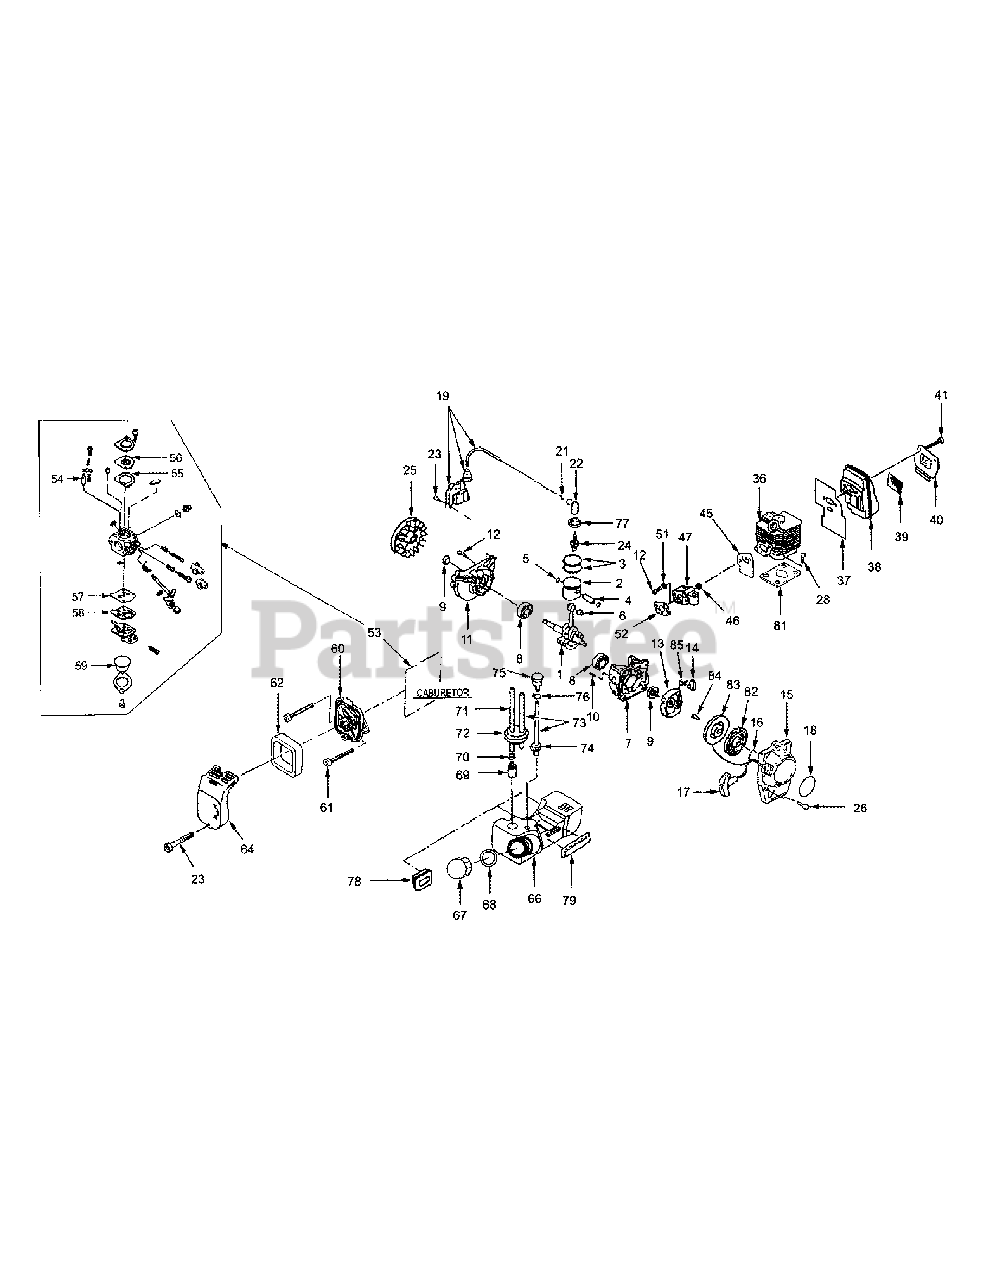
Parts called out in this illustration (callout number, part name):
2	Piston Assembly
3	Ring, Piston
5	Clip, Piston Pin
6	Bearing, Needle
7	Crankcase Assembly
8	Bearing, Ball, 6201
11	Crankcase Assembly
13	Pulley Assembly, Starter
15	Recoil Assembly
16	Rope, Starter
17	Knob, Starter
19	Coil Assembly, Ignition
24	Spark Plug
25	Flywheel, Magneto
37	Gasket, Muffler
40	Baffle Plate, Outer
45	Gasket, Insulator
47	Insulator
51	Washer
52	Gasket
53	Carburetor Assembly
54	Valve, Float
56	Diaphragm, Metering
57	Diaphragm, Pump
60	Case, Air Silencer
62	Element, Air Filter
67	Cap Assembly, Fuel Tank
69	Filter, Fuel
71	Hose
75	Valve, Reversing
79	Rubber
81	Gasket, Cylinder
82	Spring, Spiral
85	Spring, Return
